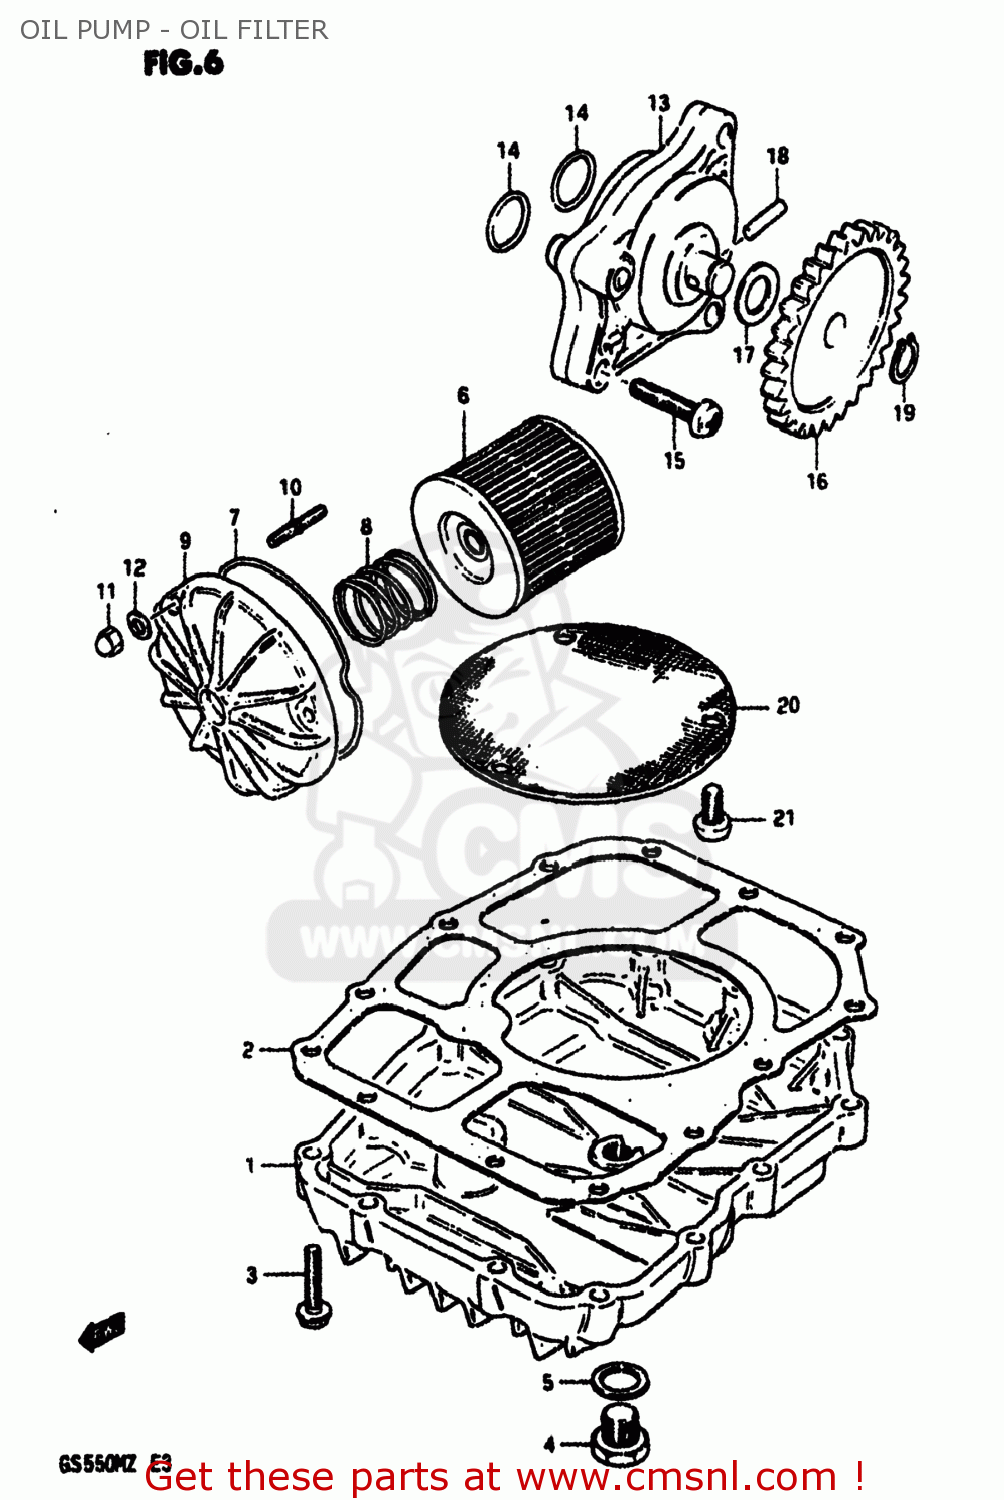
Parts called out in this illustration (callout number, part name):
1	PAN,OIL
2	GASKET,OIL PAN (MCA)
3	BOLT
4	PLUG
5	GASKET(14X19.2X2) (NAS)
6	FILTER ASSY,ENGINE OIL
7	O RING,OIL FILTER CHAMBER CAP
8	SPRING
9	CAP,ENGINE OIL FILTER
10	STUD 6X20
11	NUT
12	WASHER
13	PUMP ASSEMBLY,ENGINE OIL
14	O RING(D:1.9,ID:13)
15	SCREW
16	GEAR,OIL PUMP DRIVEN
17	SHIM
18	PIN(4X15.8)
19	CIRCLIP
20	STRAINER,ENGINE OIL
21	SCREW 6X12
